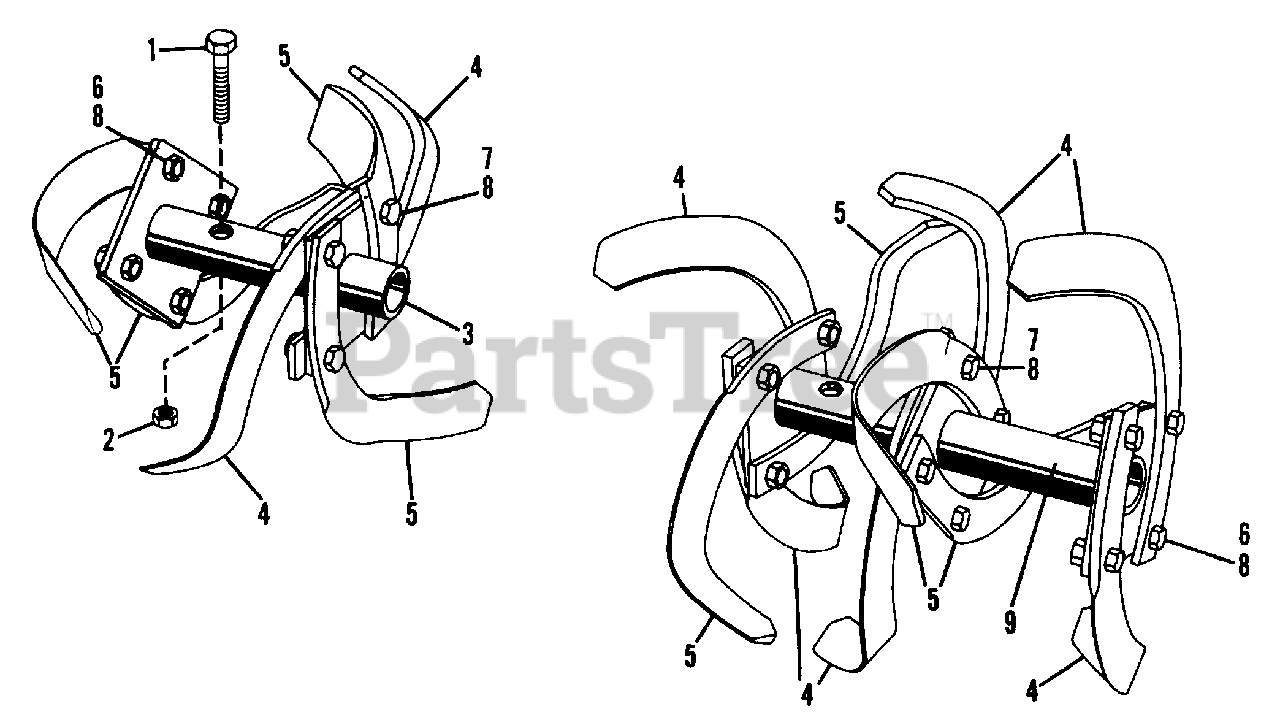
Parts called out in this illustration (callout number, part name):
1	BLT-HEX .38-16X2.00 PL GR2
2	NUT-LK-CTR .375-16 GR A PL
3	SHORT TINE TUBE WELDMENT
4	TINE L.H.
5	TINE R.H.
6	BLT-HEX .44-14X1.00 GR5
7	BLT-HEX .44-14X1.50 GR5
8	NUT-LK-TOP .437-14 GR C PL
9	LONG TINE TUBE WELDMENT
